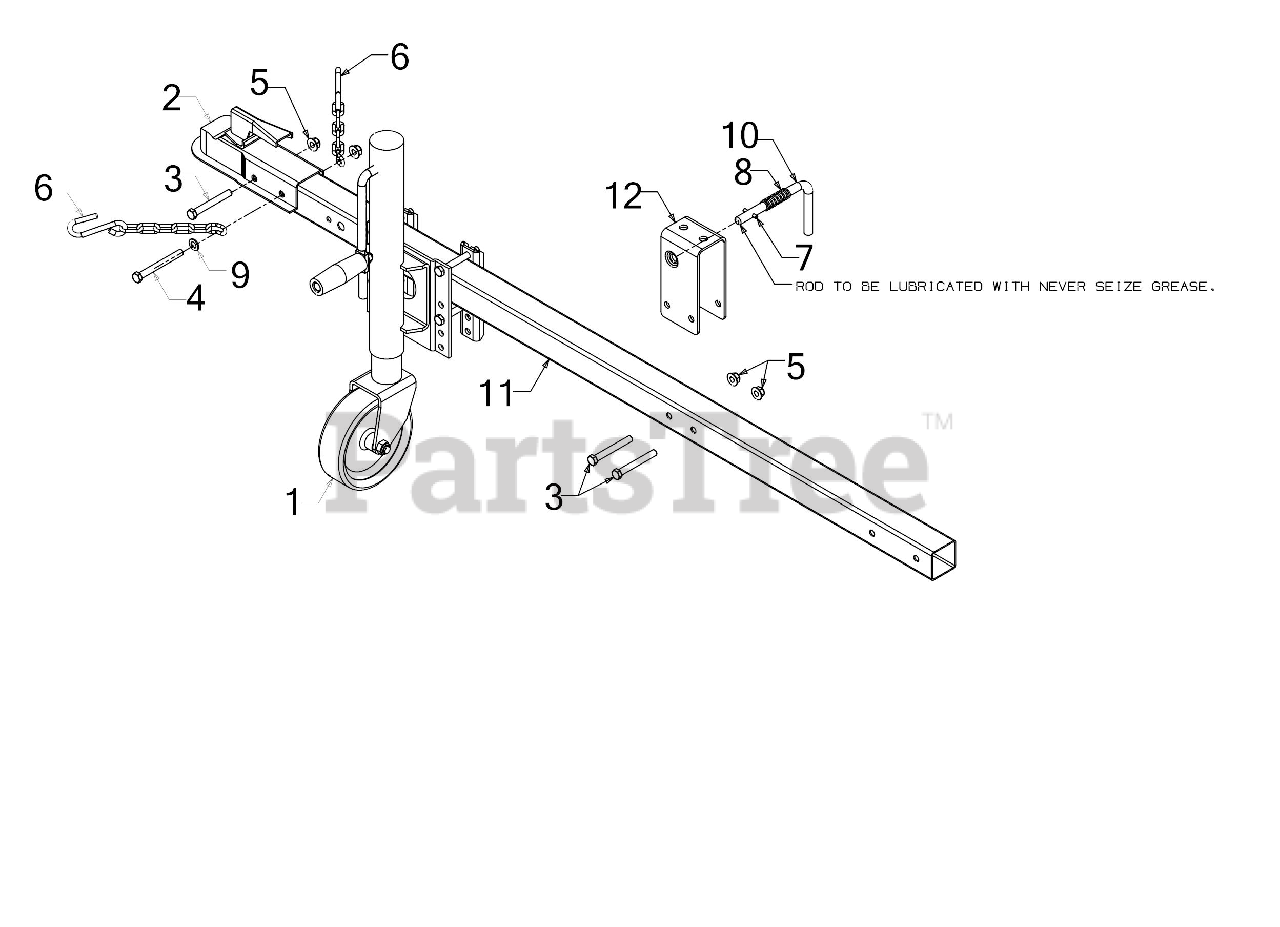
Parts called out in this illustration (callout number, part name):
1	ADJUSTING STAND
2	HITCH COUPLING ASSEMBLY
3	SCREW 3/8-16 x 3 GR8
4	SCREW 3/8-16 x 3.50 GR5
6	LOGSPLITTER TOW CHAIN
7	SPRING PIN 3/16 x 1.00
8	COMPRESSION SPRING
9	FLAT WASHER
10	LATCH ROD
11	TONGUE TUBE
